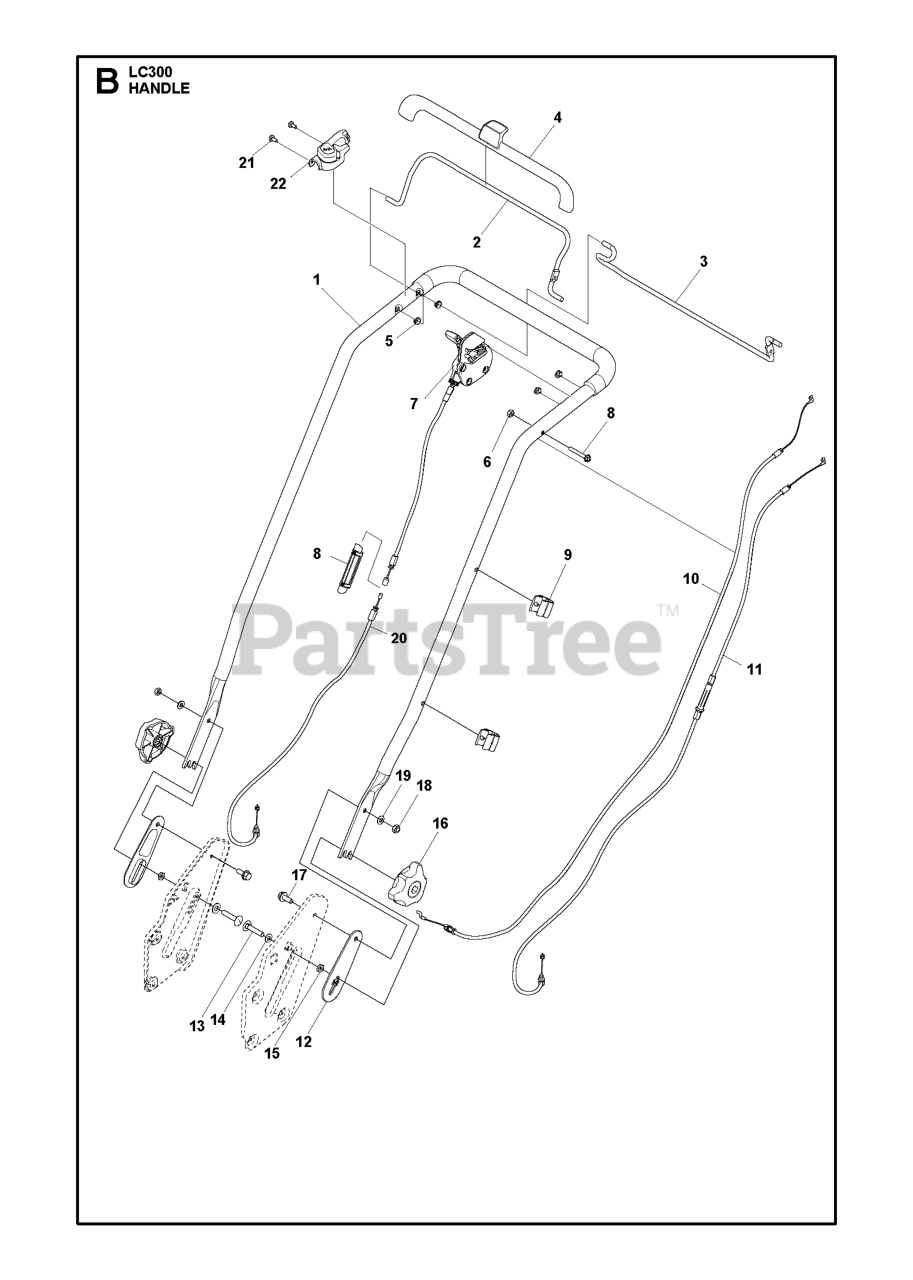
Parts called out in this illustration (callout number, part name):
1	WHEEL.STEER.HUSQ.SR.498.OVMLD
2	AXLE.SVC.ASM CAST IRON.TEX
4	SPINDLE.WELDED.LH.16"TEX
5	SPINDLE.WELDED.RH.16"TEX
6	NUT FLANGE - M6
6	THRUST WASHER
9	CAP.SPINDLE.BLACK
14	WASHER, LOCK 3/8
15	NUT ML6M M8
15	NUT CROWNLOCK 3/8-24
16	SHAFT.STEER.STEALTH.DD
18	LOCKNUT M8
19	PLATE.STEER.DDL.NLT/NG
21	SCREW ITXPANTT M5X10 ZPB (A00
21	ADAPTER.WHEEL.STEER.SPLND.ALUM
22	STEERING.SUPT.LOWER.
26	INSERT.CAP.WHL.STRG.HUSQ.PREM
28	SCREW, 3/8-16X3/4
35	GEAR.SECTOR.PLATE.DDL.
45	WASHER.3/8ID.2-3/8OD.12GA.PLTD
50	NUT LOCK FLG 3/8-16 UNC
51	NUT.HEX.1/2-20
53	WASHER.HARDENED
55	SPACER.BRACE.AXLE
58	BOLT.SHOULDER.SECTOR.P
59	WASHER.THURST.SECTOR.S
60	NUT FLANGE LOCK 5/8-11
61	DRAGLINK.LH.BALLSTUD.D
62	DRAGLINK.RH.BALLSTUD.D
63	SCREW
64	RETAINER.CLIP.SPRING.S
65	BRACE.AXLE.FRONT.NLT/N
66	BOLT HEX FGHD 7/16-14 X 3 SERR
67	BUSHING.PM.FRONT AXLE
68	NUT.LOCK.FLANGE.7/16
69	WASHER.1.5X.505X.118
70	BRKT.DECK.SUSPENSION.F
78	THRUST WASHER
118	BUSHING, AXLE CAST
122	CAP.GEAR.SECTOR.TEX
